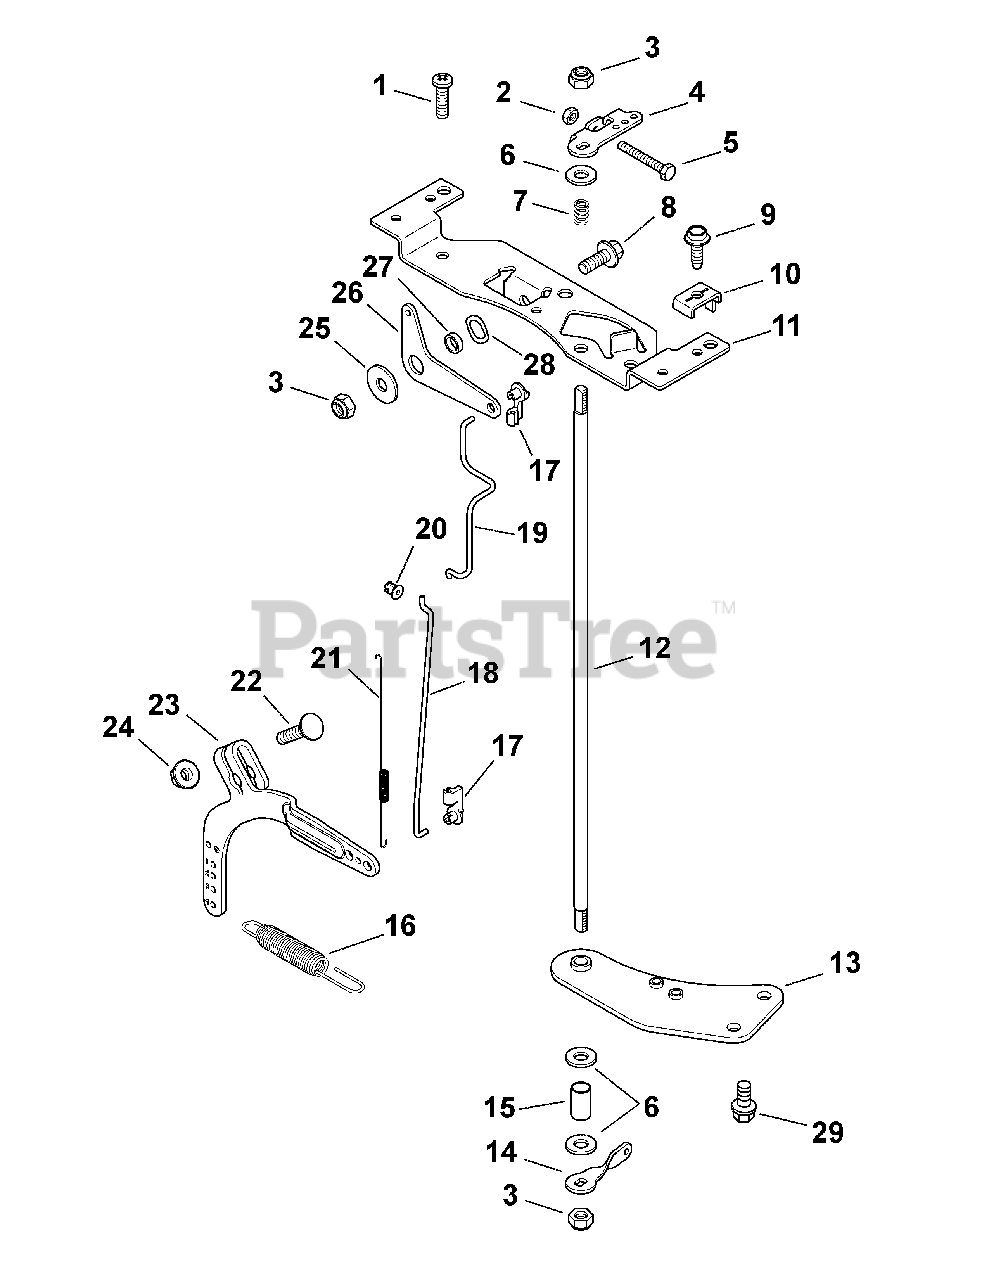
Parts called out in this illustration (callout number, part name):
1	Screw, Phl Hd 11-16X3/4"
3	Nut, Lock M6X1.0
4	Lever, Throttle Control
5	Screw, Cap M4X0.7X30
6	Washer, Flat 1/4"
7	Spring, Throttle Shaft
8	Screw, FLG M6X1.0X16
9	Screw, Flg Thd Frm M5X0.8X16
10	Clamp, Cable
11	Bracket, Control
12	Shaft, Throttle
13	Bracket, Throttle Shaft
14	Lever Throttle Control
16	Spring, Governor
17	Bushing, Throttle Linkage
18	Linkage, Throttle
19	Linkage, Choke
20	Bushing, Linkage Retaining
21	SPring, Linkage
22	Bolt, Rd Hd Sq Neck M6X1.0X25
23	Lever, Governor
24	Nut, Flg M6x1.0
25	Washer, Flat 1/4"
26	Lever, Choke
28	Washer, Spring 3/8"
29	Screw, Flg Thd Frm M6x1.0x16
